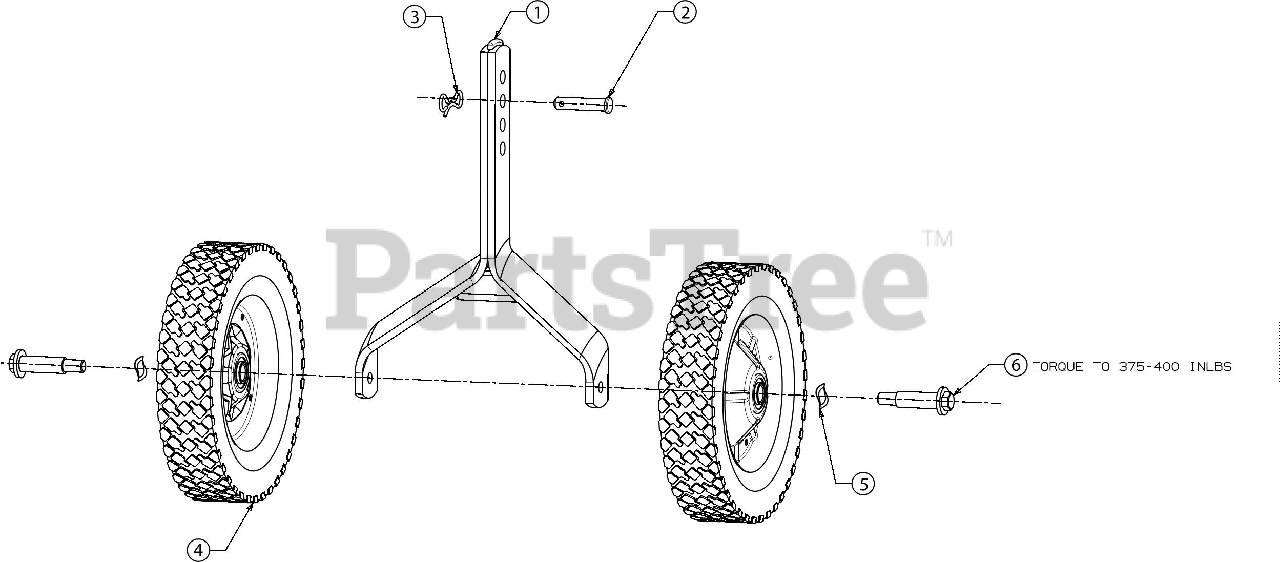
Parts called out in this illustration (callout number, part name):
1	WHEEL BRACKET ASSEMBLY
2	CLEVIS PIN .375 X .1.75
3	PIN:COTTER
4	COMPLETE WHEEL 8 X 1.75 CRAFTS GRY
4	BALL BEARING
5	WAVE WASHER
6	SHOULDER SCREW .496X1.44 3/8-16
